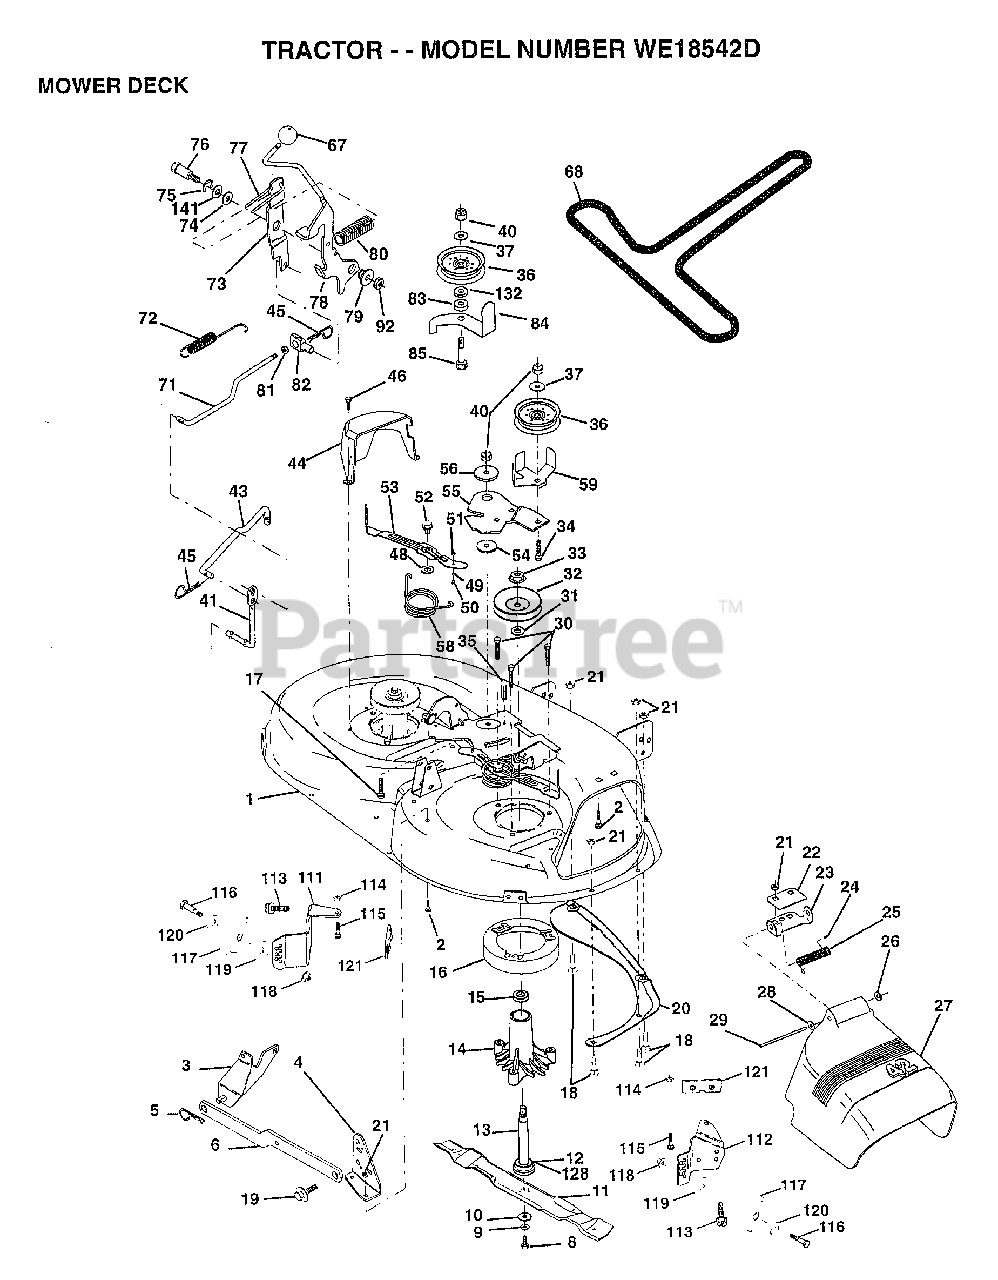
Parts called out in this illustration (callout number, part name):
1	"HOUSING ASSY.42"""
2	BOLT
3	BRKT ASM SWAY BAR
4	BRKT DECK SW BAR
8	BLADE BOLT
10	WASHER.HARD.BLADE
11	"BLADE.42"" HIPERF"
12	BEARING.BALL
14	HSG ASM MANDREL
15	BEARING
16	STRIPPER RND MWR
17	BOLT RDHD 3/8-16
18	BOLT
19	BOLT SHD 5/16-18
20	BAFFLE VORTEX 42
22	STIFFENER BRKT
23	DEFLECTOR BRKT
24	CAP-SLEEVE LT
24	NUT PUSH M
25	SPRING TORSION
27	DEFLECTOR.SHIELD
28	WASHER
29	HINGE ROD
30	"SCREW-THD ROLL,WA"
31	WASHER
32	PULLEY.MANDREL.42
34	BOLT
35	XMAS TREE FASTNER
36	FLAT IDLER PULLEY
37	WASHER
41	PIVOT ROD
43	ROD CLUTCH W/NIBS
44	GUARD MAND LH BLK
45	RETAINER M
46	SCREW.1/4-20X5/8
48	HARD SMALL WASHER
49	ROLLER ASM-CAM
50	SHOULDER BOLT
51	LOCKNUT
52	BOLT.SHLD.5/16-18
53	BRAKE PAD ARM ASM
54	HARDENED WASHER
55	ARM-IDLER
56	SPACER RETAINER
58	SPRING TORSN BRAK
59	GUARD IDLER TUV
67	KNOB.RD.7/16-14
68	BELT.V.T-PATH
71	ROD CLUTCH 38/42
72	RETURN SPRING
73	CLUTCH ARM SECOND
74	WASHER
75	RING
76	SHOULDER BOLT
77	SPRING KEEPER
78	LEVER.ASM.CLUTCH
79	BUSHING
80	SPRING.CLUTCH.MWR
81	NUT
82	TRUNION ADJ
83	WASHER
84	"KEEPER-BELT,FIXED"
85	BOLT
92	NUT
111	BRACKET.GWHL.LH.
112	BRACKET.GWHL.RH.
113	SCREW
116	BOLT M
117	WHEEL.GAGE.BLK.PL
118	LOCKNUT
119	WASHER
120	WASHER
121	BRACKET.EXTRD.GWL
128	WASHER.FELT.
132	WASHER GT
141	WASHER .T
